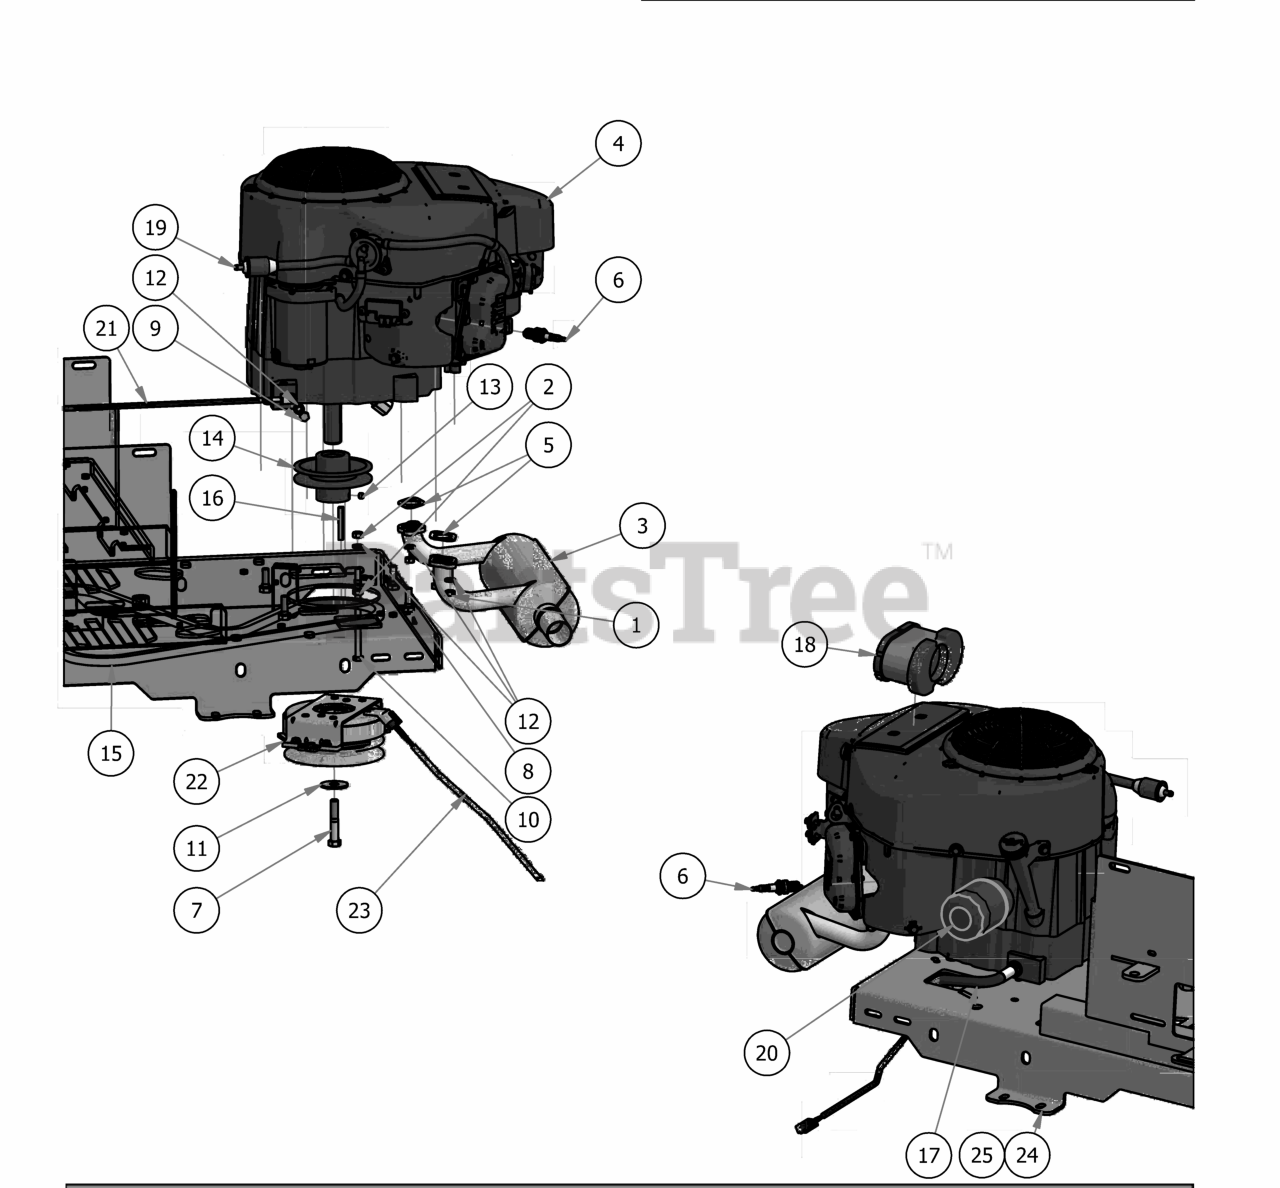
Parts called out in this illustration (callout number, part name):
1	M8-1.25 Zinc Nut
3	Kawasaki Muffler 1251
4	Kawasaki Engine-FR730V
5	Exhaust Gasket
6	Spark Plug - Kawasaki
7	7/16"-20 x 2.5" Hex Bolt Gr. 8
8	3/8 x 1 1/8 bolt
9	M8x1.20x20MM Hex head bolt
10	5/16-18 x 5-1/2 GR 5 Hex Bolt
11	1/2" Belleville Washer
12	5/16" Lock Washer
13	5/16 Set Screw
14	4 3/4 Motor Pulley
16	1/4 x 2 Square key Stock
17	Oil drain Hose
18	Kawasaki Air Filter
19	Universal Inline Fuel Filter
20	Kawasaki Oil Filter
21	24" Black Ground Cable
23	Clutch Pigtail
24	2017 MZ/ZT 54"-60" Frame
25	2017 MZ/ZT 42"-48" Frame
